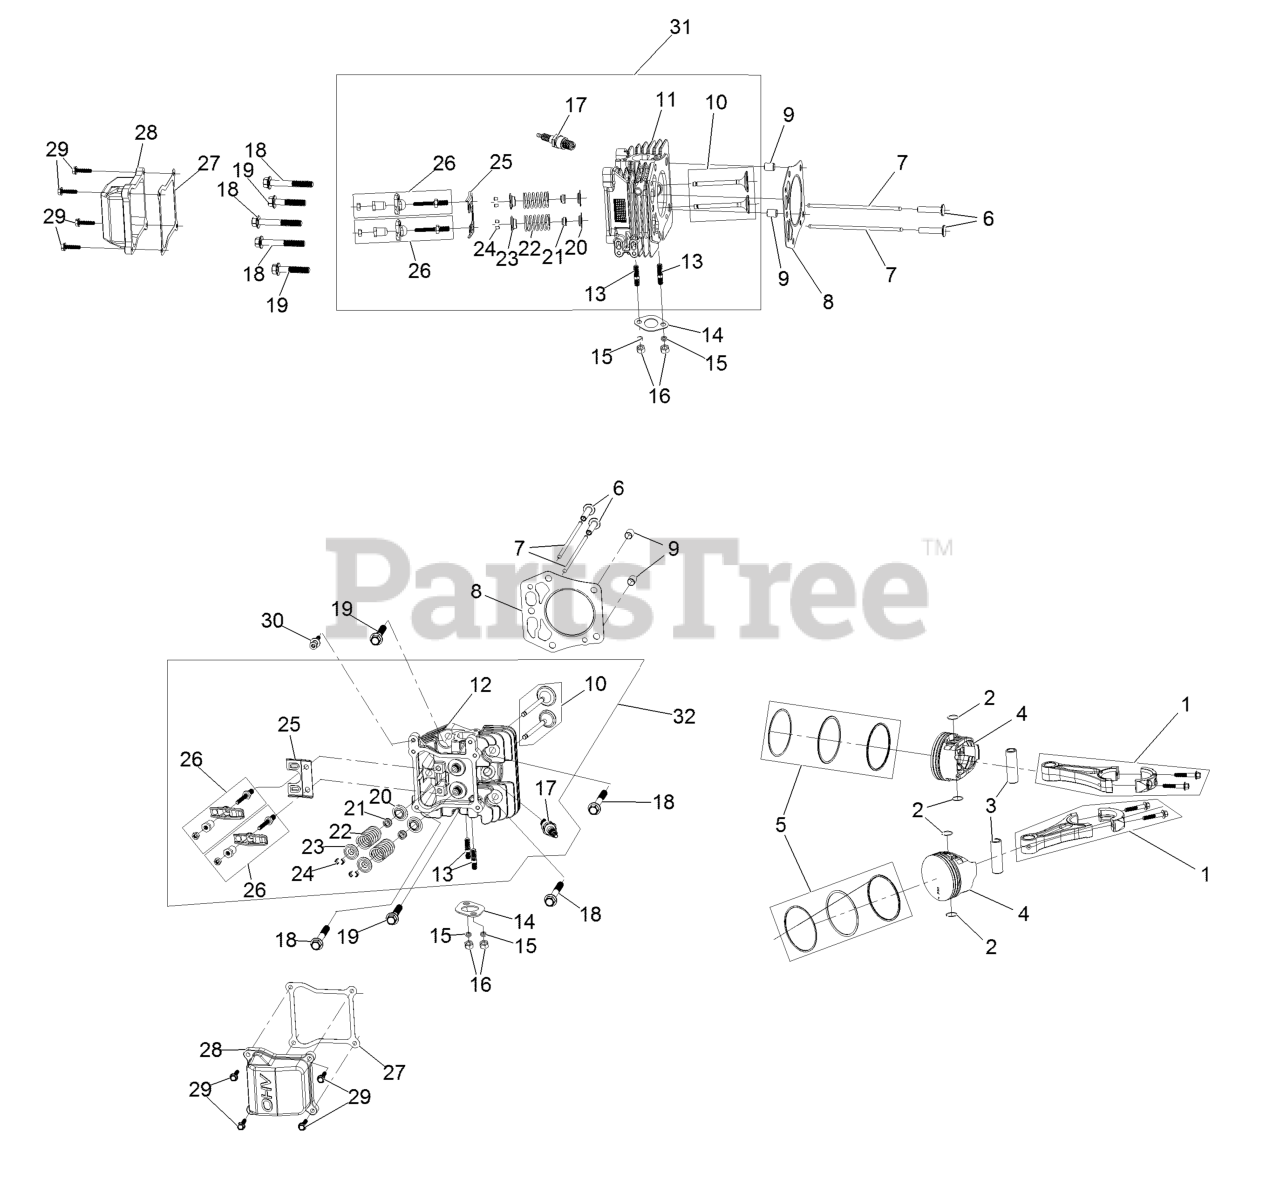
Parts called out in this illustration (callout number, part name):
1	Connecting Rod ASM
2	Clip-Pin, Piston
3	Pin-Piston
5	Piston Ring Set
6	Lifter-Valve
7	Rod-Push
8	Gasket-Head, Cylinder
9	Pin-Dowel
10	Valve Set
11	Head-Cylinder
12	Head-Cylinder
13	Stud-Exhaust
14	Gasket-Exhaust
15	Washer-Lock, Split
16	Nut-Hex M8
17	Spark Plug
18	Screw-HWH
19	Screw-HWH
20	Seat-Spring, Valve
21	Seal-Stem, Valve
22	Spring-Valve
23	Retainer-Spring, Valve
24	Keeper-Valve
25	Plate-Guide, Push Rod
26	Rocker Arm ASM
27	Gasket-Valve Cover
28	Cover-Valve
29	Screw-HHF
30	Screw-Shoulder, HH
31	Complete Right Head ASM
32	Complete Left Head ASM
